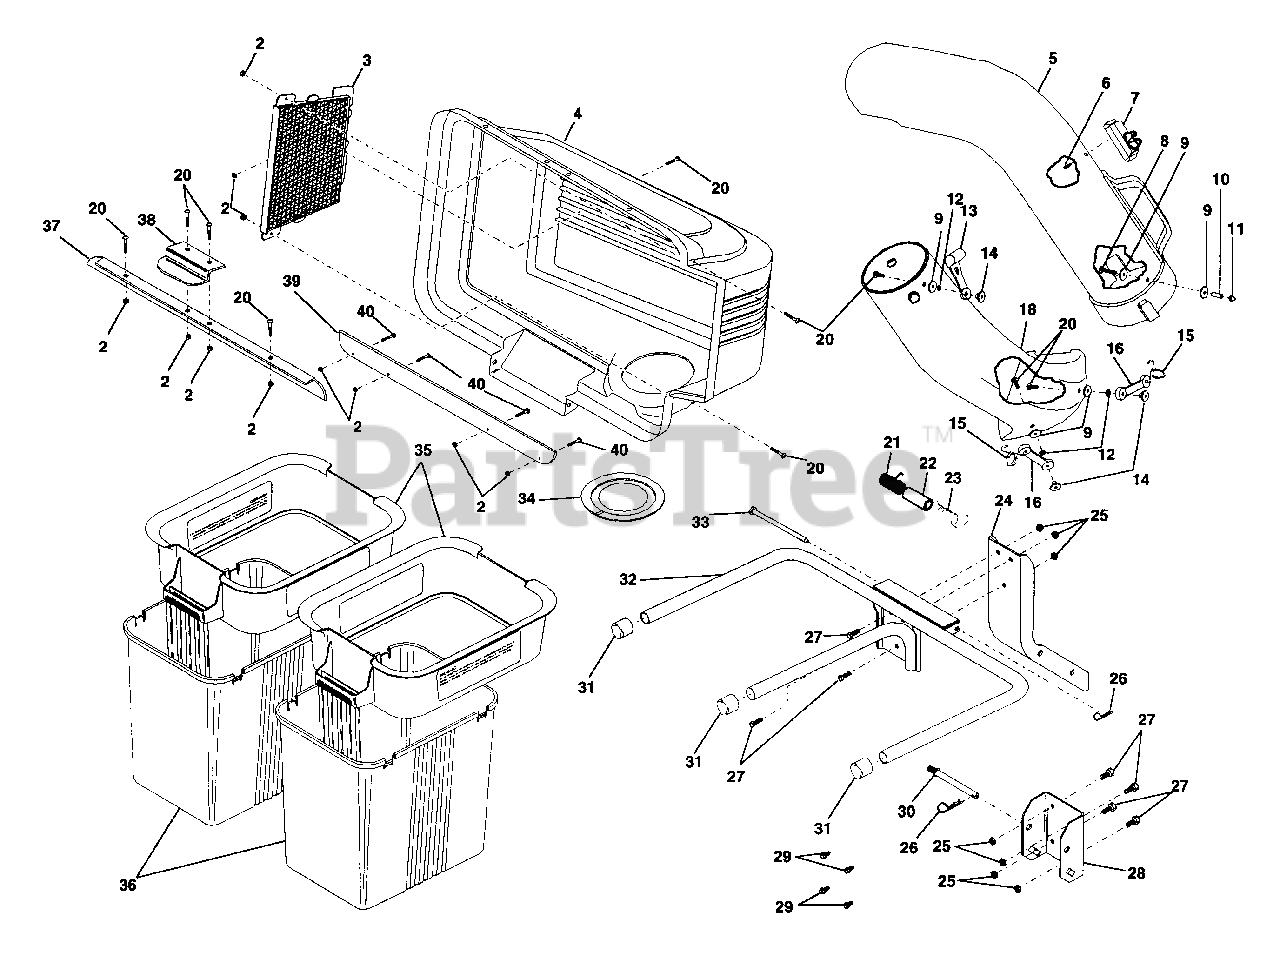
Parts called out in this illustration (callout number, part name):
2	Nut, Crownlock #10-24
3	Screen, Cover
4	Cover
5	Chute, Upper
6	Screw, Special #10-14 x 1/2
7	Dump Bag Indicator
8	Screw, #10-24 x 1-1/8
9	Washer 3/16 x 3/4 x 16 Ga.
10	Spacer, Split
11	Nut, Acorn #10-24
12	Washer, lock
13	Latch, Chute
14	Nut, Weld
15	Latch, Hook
16	Rubber, Latch
18	Chute, Lower
20	Screw #10-24 x 5/8
21	Spring, Cover L.H. (black)
22	Spacer, Cover
23	Spring, Cover R.H. (gray)
24	Post, Support
25	Locknut 5/16 x 18
26	Spring, Retainer
27	Bolt, Hex 5/16-18 x 3/4
28	Bracket, Mounting
29	Screw 5/16-18 x 1/2 Hex, Self Tapping
30	Pin, Support Post
31	Plug, Tubing End
32	Bagger, Frame
33	Pin, Hinge
34	Gasket, Cover
35	Container, Top
36	Container, Bottom
37	Seal, Cover
38	Latch Handle, Cover
39	Strip, Seal
40	Screw #10-24 x 1/2
